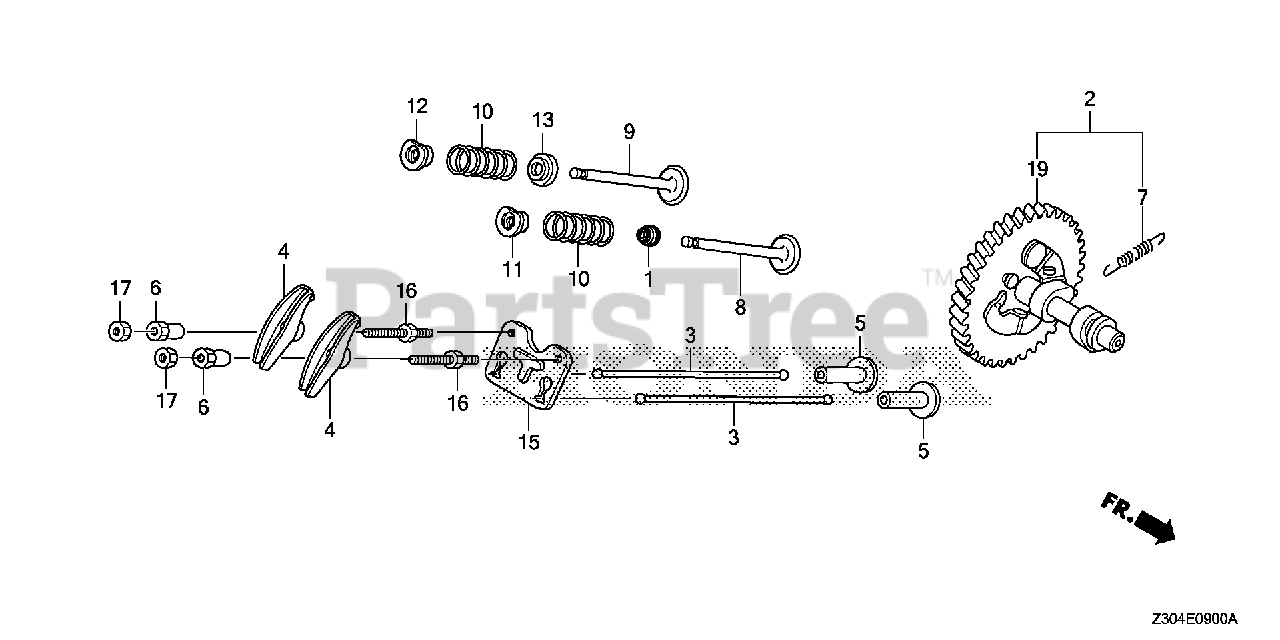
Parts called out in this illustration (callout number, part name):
1	SEAL, VALVE STEM
4	ARM, VALVE ROCKER
5	LIFTER, VALVE
6	PIVOT, ROCKER ARM
8	VALVE, IN.
9	VALVE, EX.
10	SPRING, VALVE
11	RETAINER, IN. VALVE SPRING
12	RETAINER, IN. VALVE SPRING (EXHAUST SIDE)
13	SEAT, VALVE SPRING
15	GUIDE, PUSH ROD
16	BOLT, PIVOT (8MM)
17	NUT, PIVOT ADJUSTING
19	CAMSHAFT (STD)
